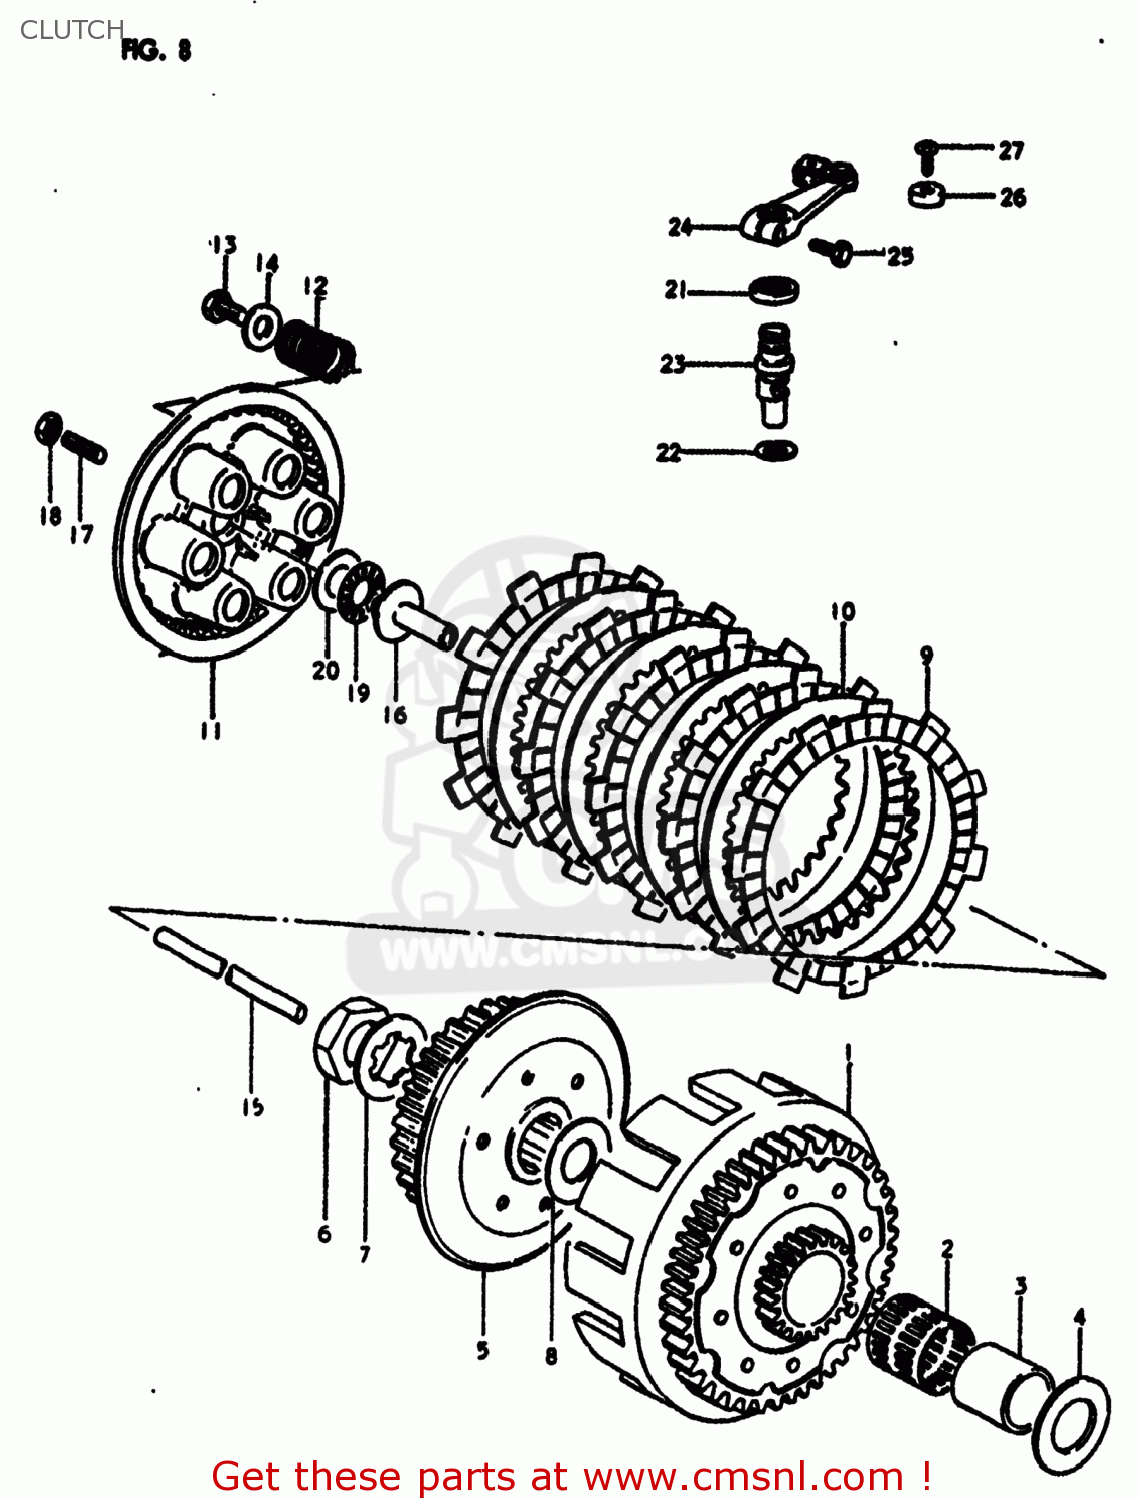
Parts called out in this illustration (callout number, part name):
1	GEAR ASSEMBLY,PRIMARY DRIVE
2	ROLLER BEARING (25X30X2
3	SPACER
4	WASHER(20X38X2)
5	HUB,CLUTCH SLEEVE
6	NUT (20MM)
7	WASHER,LOCK
8	WASHER(20X38X2)
9	PLATE,CLUTCH DRIVE (MCA)
10	PLATE,CLUTCH DRIVEN (NAS)
11	DISC,CLUTCH PRESSURE
12	SPRING
13	BOLT, UPPER
14	WASHER
15	ROD,CLUTCH PUSH
16	PIECE,CLUTCH PUSH
17	SCREW
18	NUT 6MM
19	BEARING(15X28X2)
20	WASHER
21	OIL SEAL
22	WASHER (14.2X22X1)
23	SHAFT,CLUTCH RELEASE C
24	ARM,CLUTCH RELEASE
25	BOLT
26	GUIDE,CLUTCH CABLE
27	SCREW
